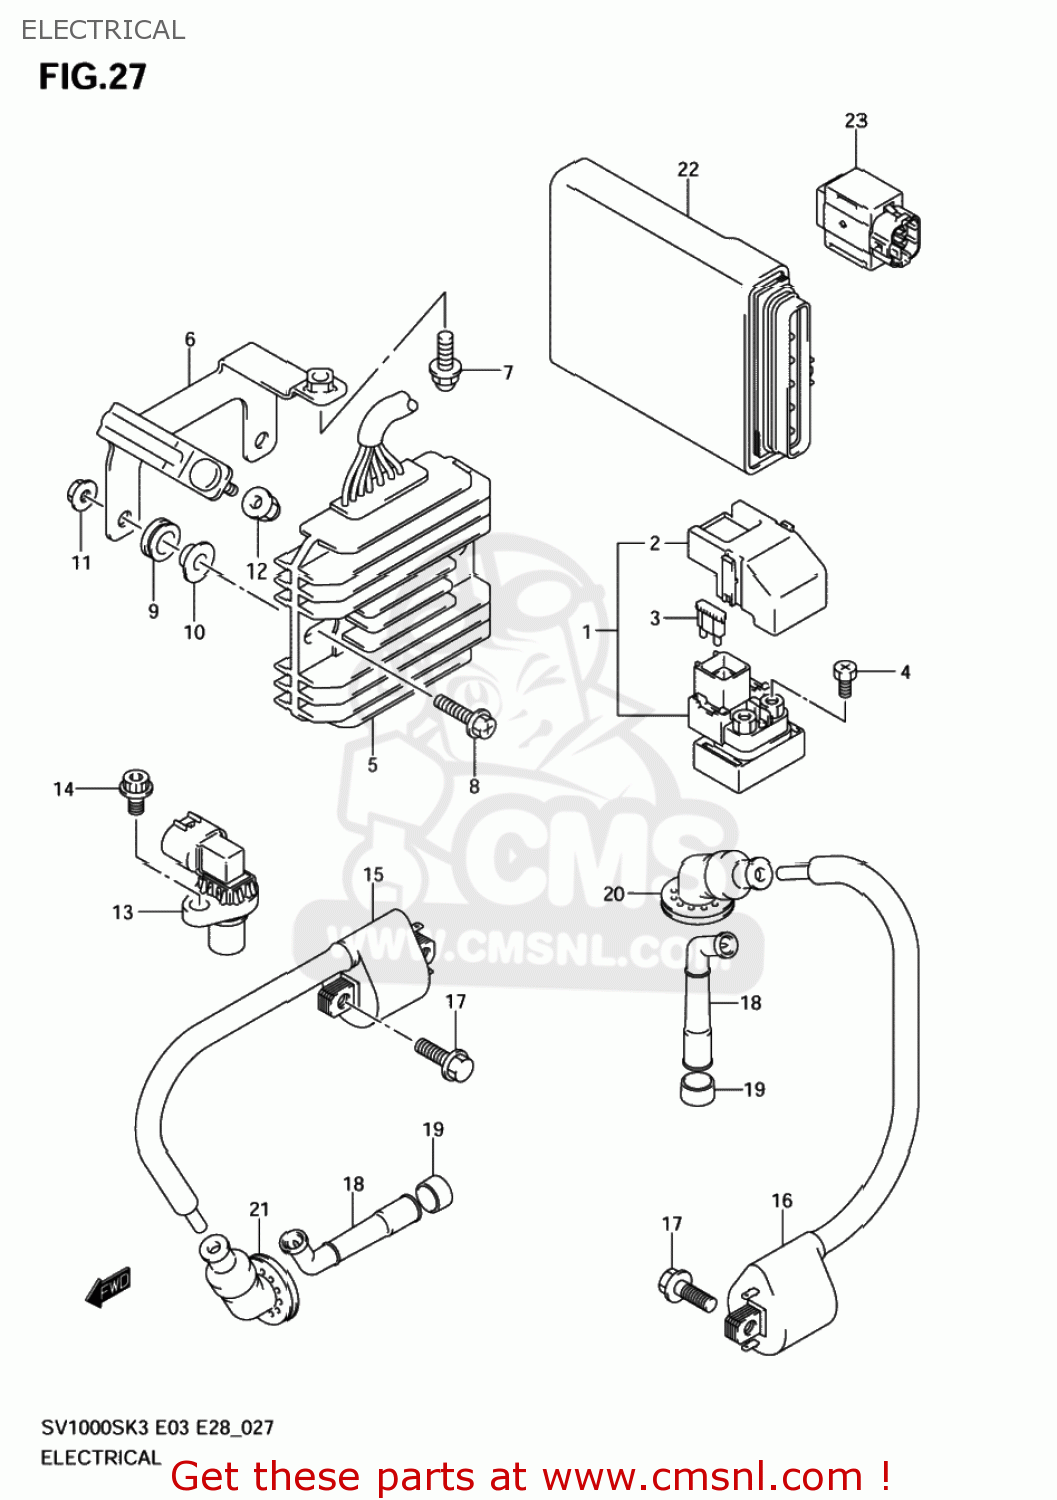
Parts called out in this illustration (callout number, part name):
1	RELAY ASSY,STARTING MOTOR
2	COVER
3	FUSE(30A)
4	SCREW(6X8)
5	RECTIFIER ASSY
6	BRACKET,RECT FTG
7	BOLT(6X15)
8	BOLT (GREEN)
9	CUSHION
10	SPACER(6.2X8.4X6.9)
11	NUT
12	NUT
13	SENSOR ASSY,CRANK POSITION
14	BOLT,OIL FILLE
15	COIL ASSY,IGNITION
16	COIL ASSY,IGNITION
17	SCREW
18	CAP ASSY,SPARK PLUG
19	SEAL,SPARK PLUG CAP
20	SEAL,HIGH TENSION CORD RR
21	SEAL,HIGH TENSION CORD FR
22	CONTROL UNIT,FI
23	SENSOR ASSY,FUEL CUT
